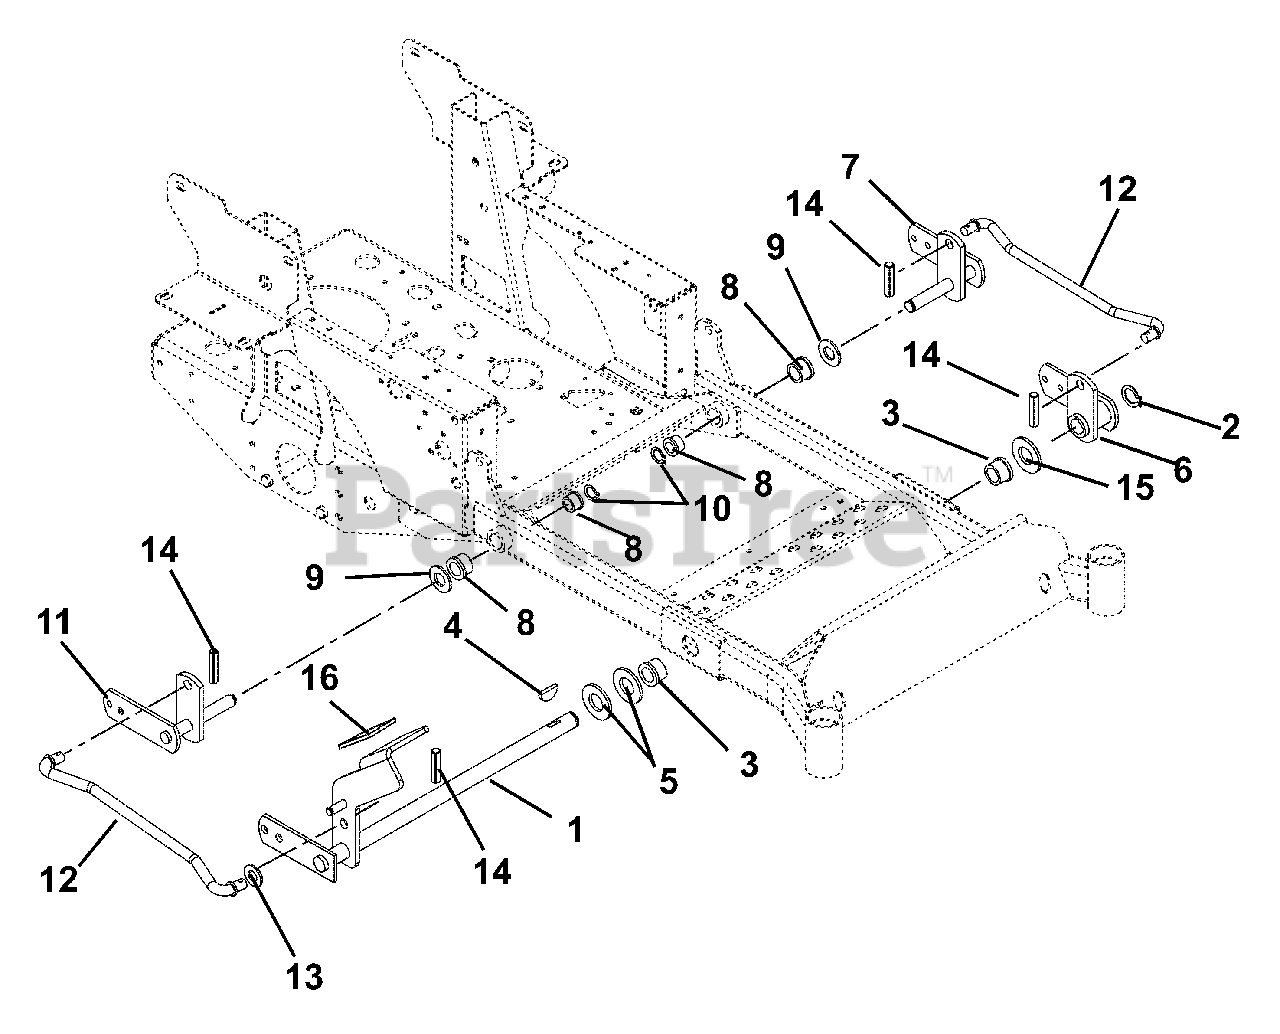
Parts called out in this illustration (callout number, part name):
1	WMT, FRONT MOWER LIFT
2	RG-RTNG-EXT 1.00X.078
3	BSHG-FLG1.020X1.385X.75X1.75NY
4	KEY-WDRF .25X1.00 HRD #15
5	WSHR-FL-STL- 1.062X2.0X.134 YZ
6	WMT, FRONT MOWER LIFT-LH
7	WMT, REAR LIFT ARM -LH
8	BSHG-FLG .762X1.0X.580X1.48 NY
9	WSHR-HDND-THRST .758X1.23X.031
10	RG-RTNG-EXT .689X.078
11	WMT, REAR LIFT ARM - RH
12	ROD, LIFT ASSIST 16.35"
13	@WSHR-FL-STL.656X1.31X.095 YWZ
14	PIN-ROLL .250X1.25 STNLESS STL
15	WSHR-HDND-THRUST 1.00X1.55X.03
16	GRIP, PEDAL 1.50 X 3.00
